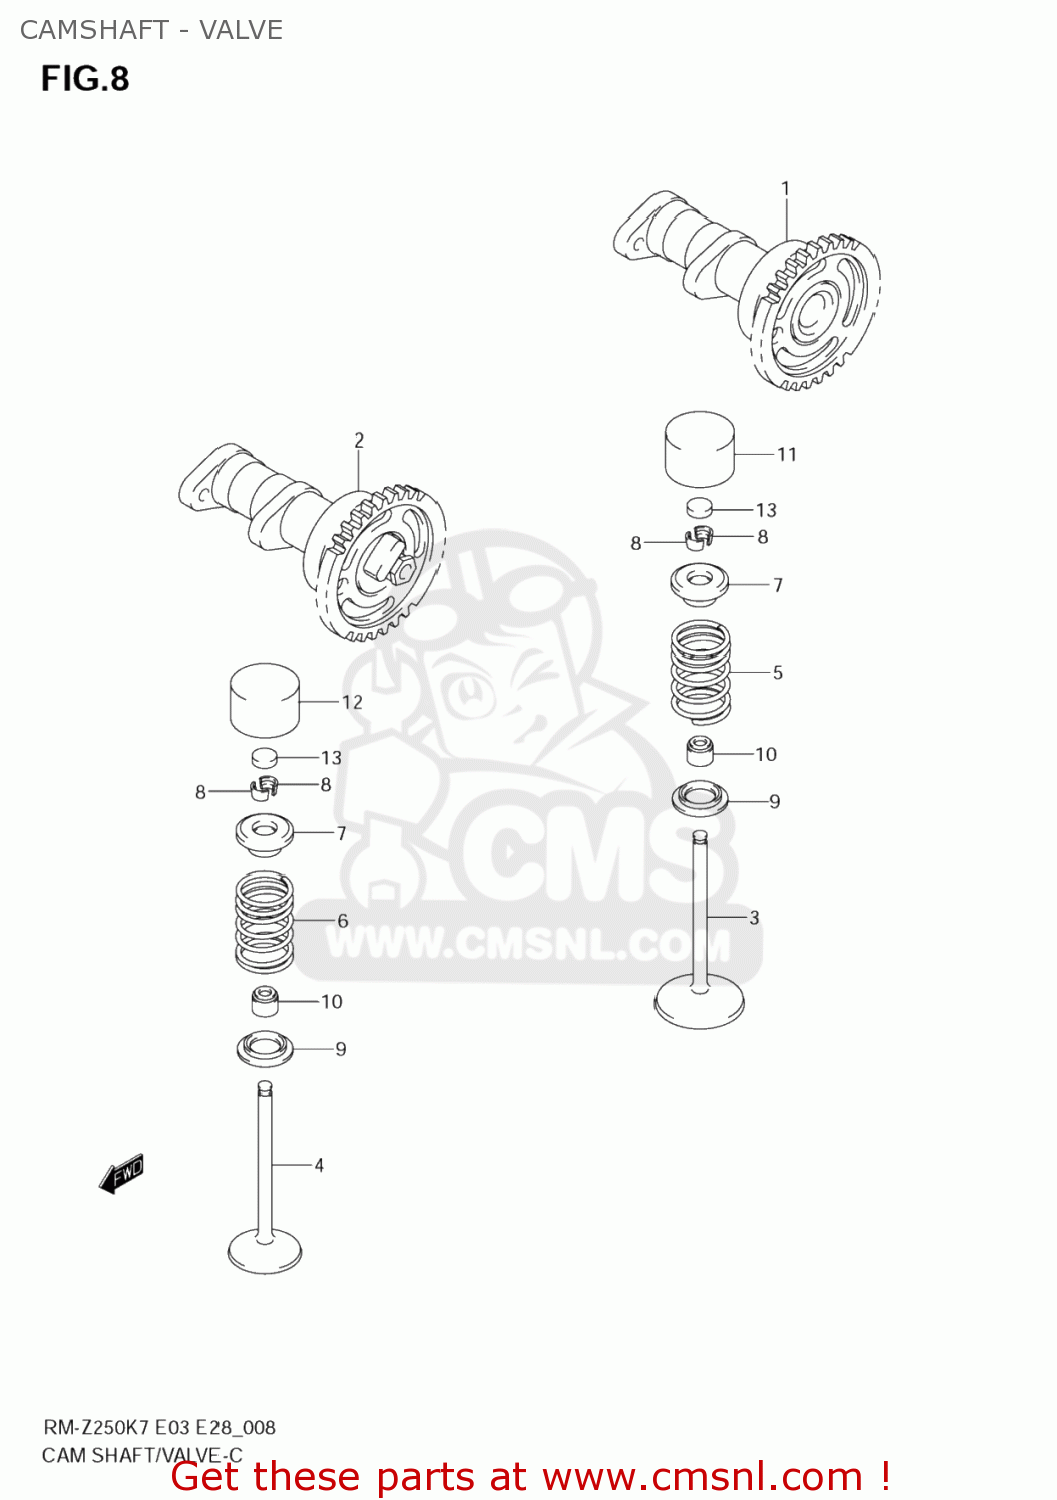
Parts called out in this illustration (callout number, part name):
1	CAMSHAFT,INTAKE
2	CAMSHAFT,EXHAUST
3	VALVE,INTAKE
4	VALVE,EXHAUST
5	SPRING,VALVE
6	SPRING,VALVE
7	RETAINER,VALVE SPRING
8	COTTER VALVE
9	SEAT,VALVE SPRING
10	SEAL,OIL(4.5X10X8)
11	TAPPET
12	TAPPET,EXHAUST
13	SHIM,TAPPET
14	SHIM SET,TAPPET
15	CASE,TAPPET SHIM
